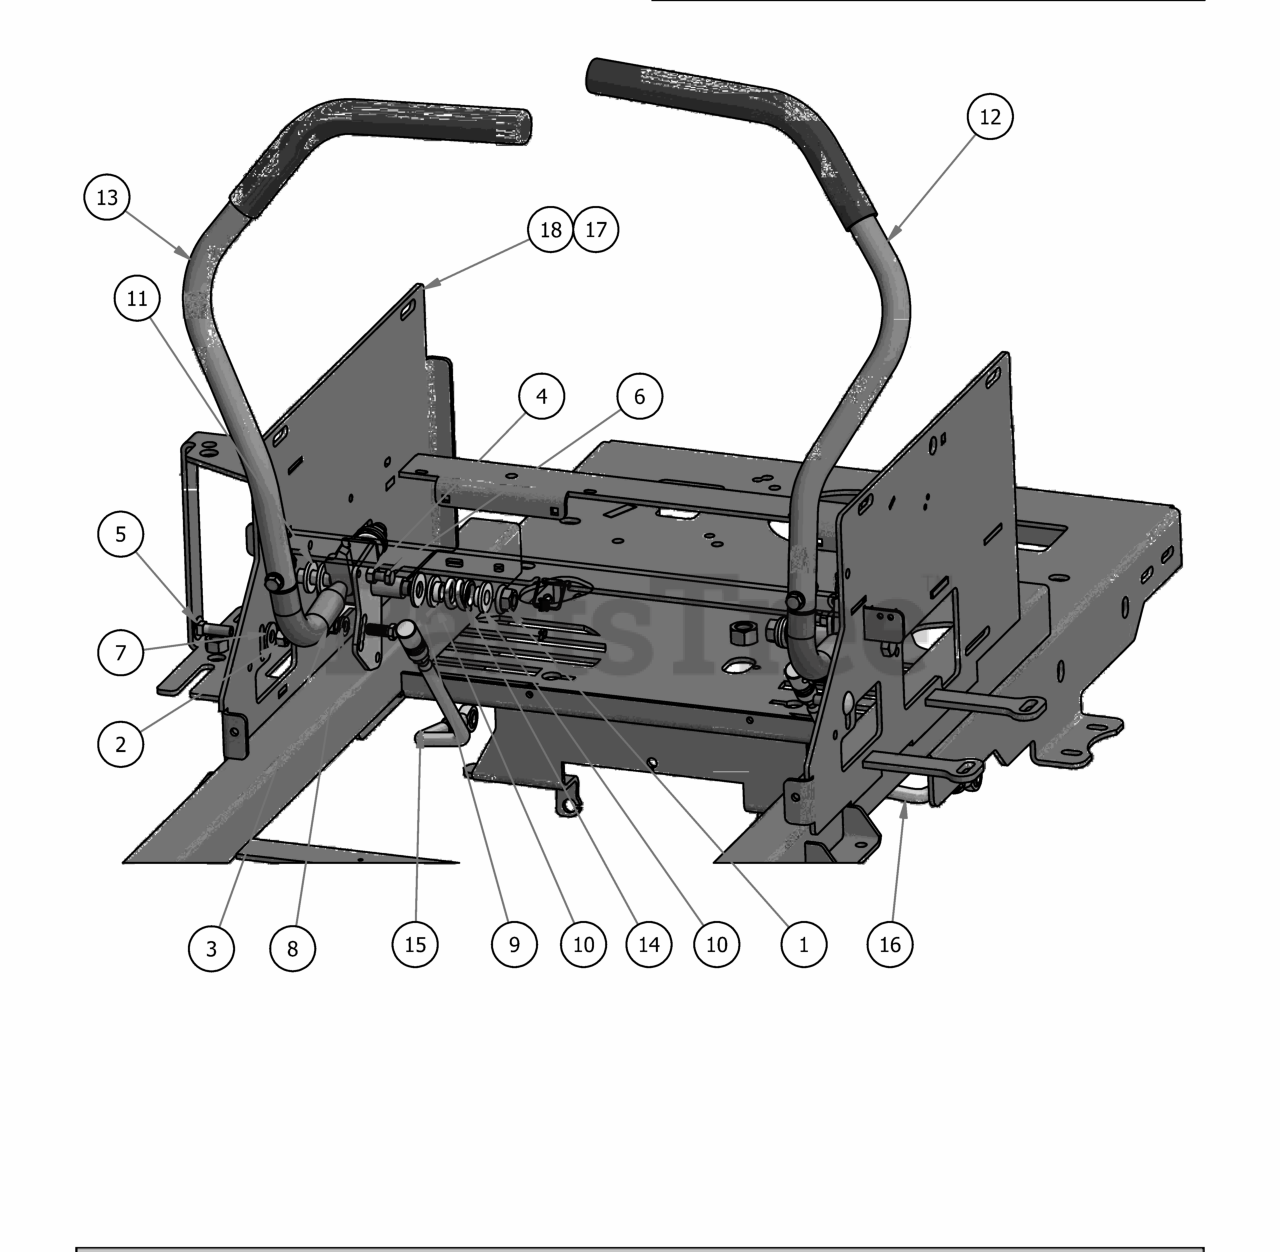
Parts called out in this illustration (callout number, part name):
1	1/2-13 Mechanical Lock Nut
2	3/8" Hex Nut
3	3/8" Fine Threaded Jam Nut
5	3/8" x 1 1/4" Carriage Bolt
6	5/16" x 3/4" Hex Bolt
7	3/8" Flat Washer
8	3/8" Lock Washer
9	1/2" Washer (Grade 8)
10	.515 ID Nylon Shoulder Washer
11	.505 Nylon Spacer
12	2017 MZ Magnum LH Steering Arm
13	2017 MZ Magnum RH Steering Arm
14	Drive Lever Spring
15	Push Rod-Right
16	Push Rod-Left
17	2017 MZ/ZT 54"-60" Frame
18	2017 MZ/ZT 42"-48" Frame
